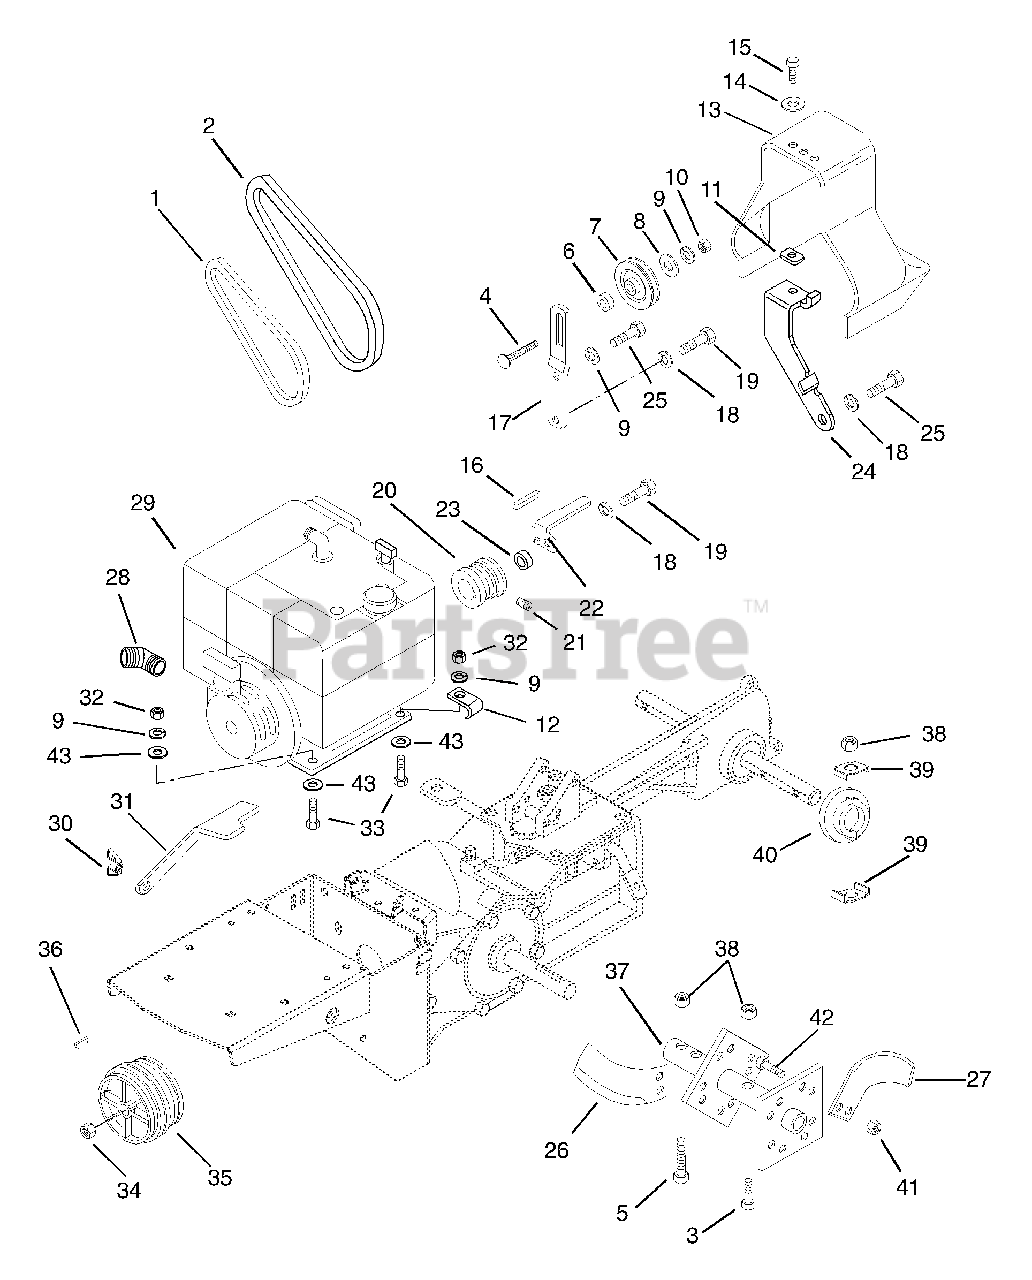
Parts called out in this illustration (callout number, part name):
1	V-BELT, SAE 380-RAW EDGE (SET)
2	V-BELT, 3L-COGGED
3	BLT-HEX .38-16X2.00 GR8 YWZC
4	@BLT-RDHDSQNK .31-18X1.50 G5YZ
5	BLT-HEX .38-16X2.75 GR8 YWZC
6	SPCR, BRG .315X.50X.688X.281
7	IDLER
8	@WSHR-FL-STL.38X.875X.083 YWZC
9	@WSHR-LK .31X.078 REG YWZC
10	@NUT-HEX .31-18 YWZC
11	NUT-SPEED U-TYPE .250-20
12	J-CLAMP
13	BELT GUARD W/DECALS
14	@WSHR-FL-STL.281X.62X.065 YWZC
15	@BLT-HEX .25-20X.50 GR5 YWZC
16	KEY-SQ .25 X 1.25 X .25 SAE
17	REVERSE IDLER BRACKET
18	@WSHR-LK .38X.094 REG YWZC
19	@BLT-HEX .38-16X.75 GR5 YWZC
20	ENGINE SHEAVE
21	SCR-SET .31-18X.38 SKHCUPDL
22	BELT FINGER
23	BSHG-SLV .391X.688X.140
24	BELT COVER BRACKET
25	BLT-HEX .31-24X.75 YWZC GR5
26	R KNIFE TINE
27	L KNIFE TINE
28	ELBOW .375X45 STREET
29	ENGINE BRIGGS 8HP IND.
30	NUT-NYLK WING .312-18 YWZC
31	BELT FINGER
32	@NUT-HEX .31-18 YWZC
33	@BLT-HEX .31-18X2.00 GR5 YWZC
34	NUT-JAM CTRLK .75-16 YWZC
35	DRIVE SHEAVE
36	KEY-FTHR .188X1.25X.187 SAE
37	INNER TINE HUB
38	@NUT-LK-CTR .38-16 YWZC
40	DUST CAP
41	@NUT-LK-CTR .44-14 YWZC
42	@BLT-HEX .44-14X1.00 GR5 YWZC
43	@WSHR-FL-STL.38X.875X.083 YWZC
